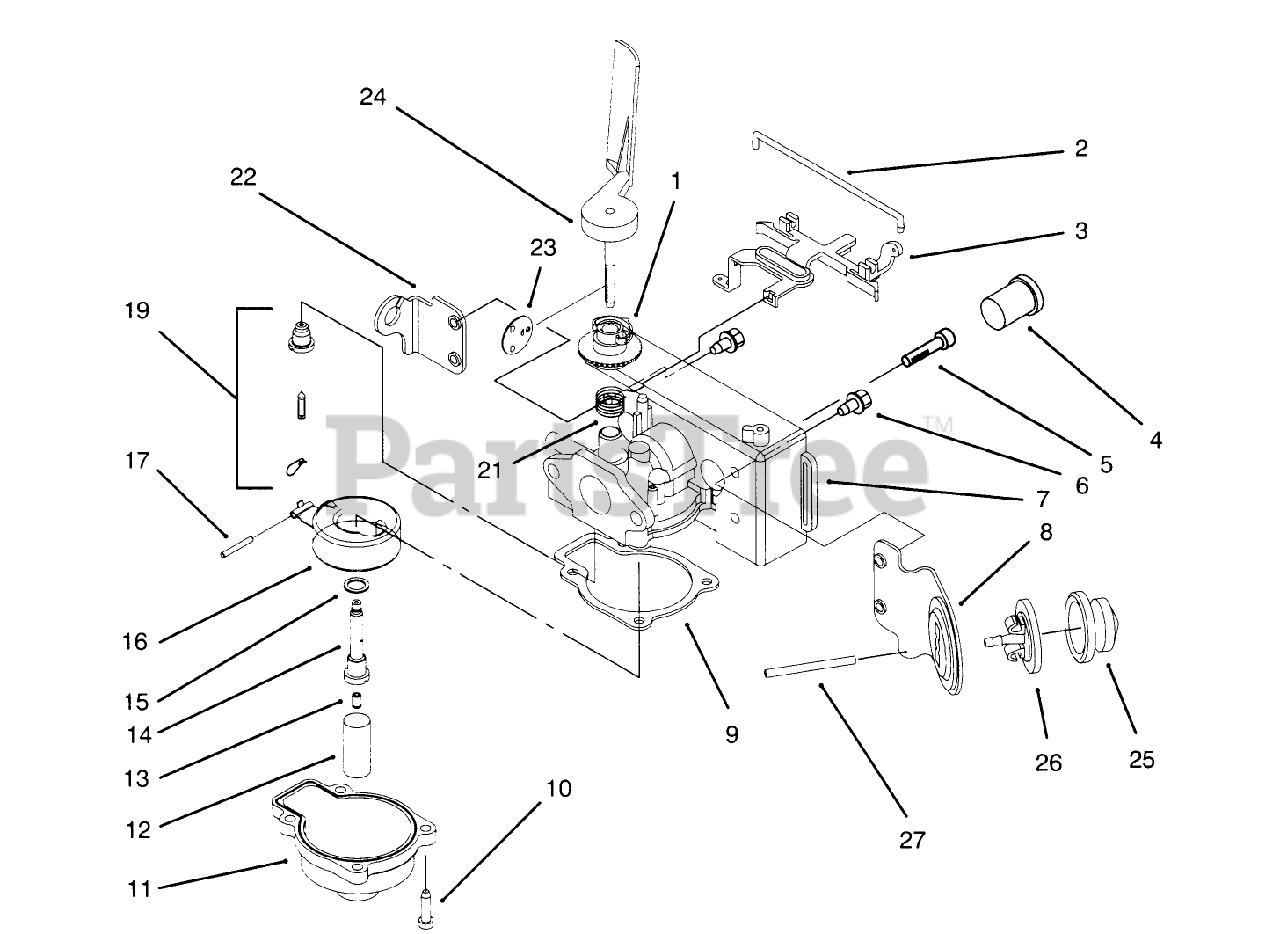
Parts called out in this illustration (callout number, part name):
1	COLLAR-ADJUST, AIRVANE
2	RETAINER
3	LEVER-ADJ. VF
8	BRKT-PRIMER F
10	SCREW-HH
11	CHAMBER-FLOAT
12	FILTER-FUEL VS
13	JET-MAIN VF
17	PIN-STRAIGHT
19	VALVE / SEAT-FLOAT
21	SPRING-GOV V
23	DISC-THRO. V
25	BULB-PRIMER
26	BODY-PRIMER
